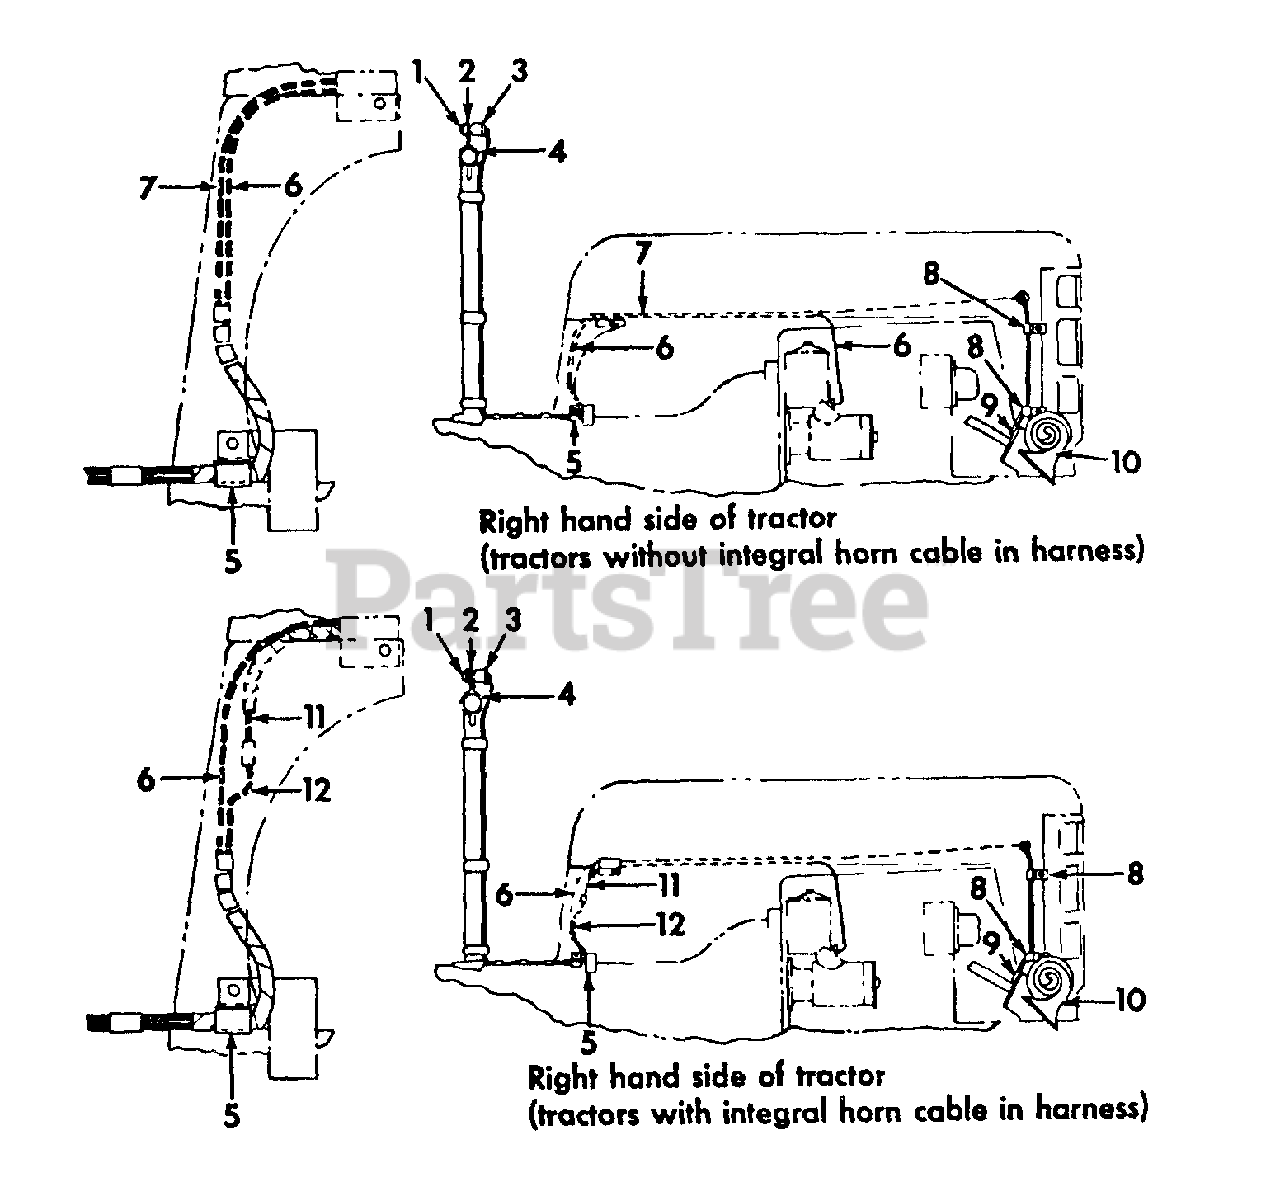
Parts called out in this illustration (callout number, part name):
1	CAP, HORN SWITCH DUST -GRAY-
2	BRACKET, HORN SWITCH MOUNTING
3	SWITCH ASSY, HORN -LESS CAP-
4	CLAMP ASSY, HORN SWITCH MOUNTING BRACKET
5	CLIP CABLE
6	CABLE, HORN SWITCH TO STARTING SWITCH
6	CABLE, HORN SWITCH TO CHARGE INDICATOR
7	CABLE ASSY, HORN SWITCH TO HORN
8	CLIP, CABLE
9	BRACKET, HORN MOUNTING
10	HORN ASSY -LOW PITCH-
11	CABLE, HORN TO CONNECTOR -DARK GREEN-
12	CABLE ASSY, HORN SWITCH TO LINE CONNECTOR
